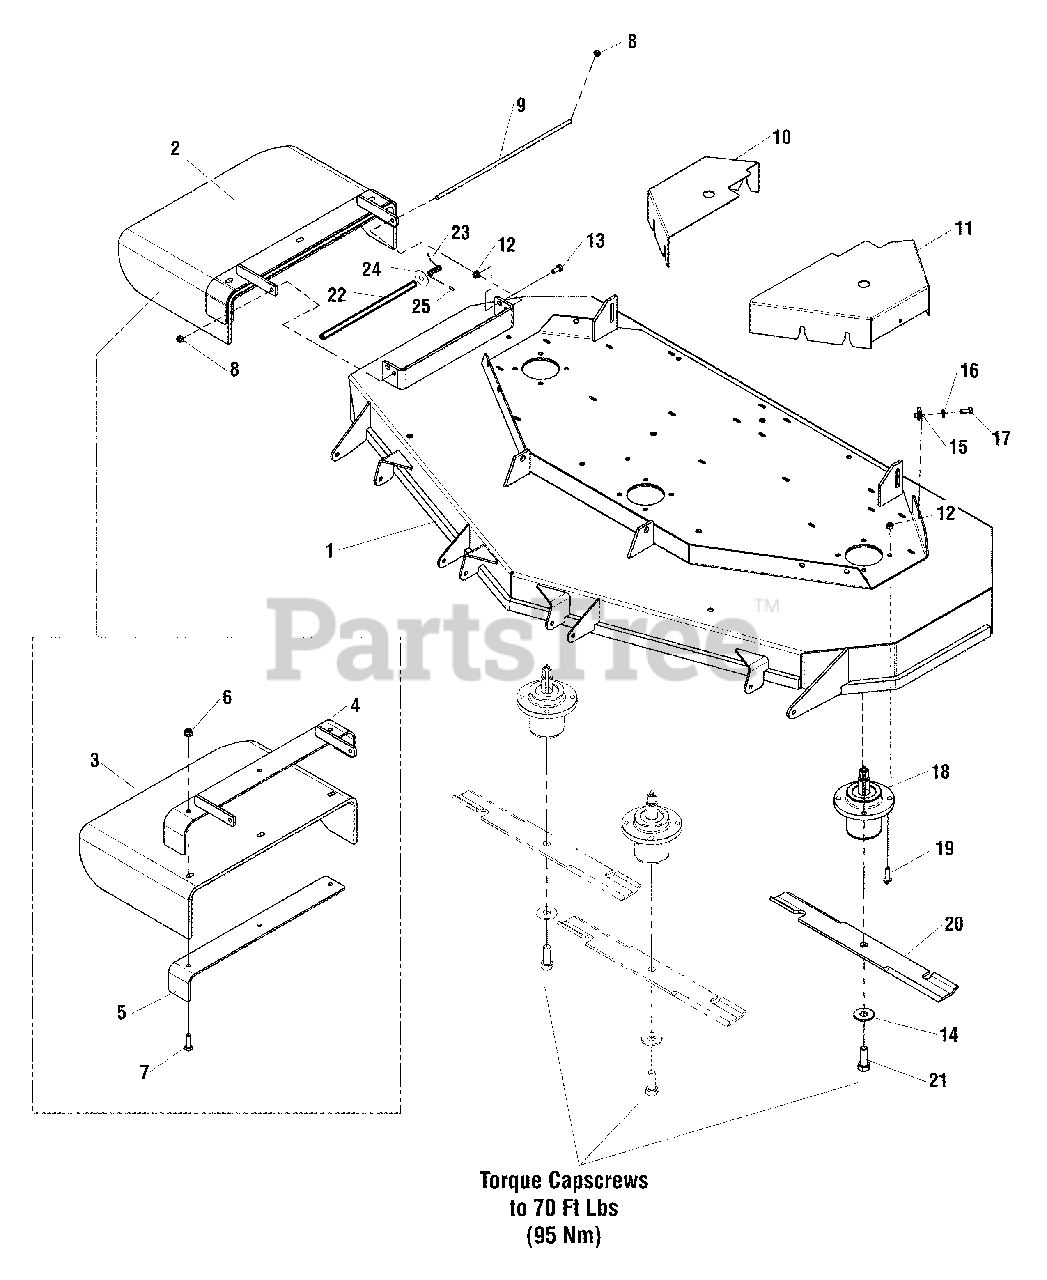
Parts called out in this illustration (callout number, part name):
1	DECK SHELL W/DECALS, 61" - ORANGE
2	ORDER INDIVIDUAL PIECES TO SERVICE DISCHARGE CHUTE COMPONENTS
3	CHUTE, DISCHARGE, RUBBER, 61
4	WELD, FRAME, CHUTE, 61 - ORANGE
5	SUPPORT, DISCHARGE CHUTE - BLK
6	NUT, 3/8-16 HEX NYLOCK FLANGE
7	BOLT, 3/8-16 X 1-1/4" GD5
8	NUT, 5/16-24 HEX NYLON LOCK
9	ROD MOUNT, CHUTE 61"
10	GUARD, 61", RH - ORANGE
11	GUARD, 61" - LH - ORANGE
12	NUT, 5/16-18 HEX NYLOCK FLANGE
13	SCREW-HEX WZ LOCK FLNG 5/16-18X0.750BLK
14	WASHER, 5/8" USS
15	BODY CLIP, 5/16-18 X 1/2" DEEP
16	WASHER, 5/16" SAE
17	BOLT, 5/16-18 X 3/4" GD5
18	ASSM, SPINDLE, LOW PROFILE
19	BOLT, 5/16-18 X 1 1/4" FLANGE
21	BOLT, 5/8-11 X 1-3/4" GD8
22	TORSION SPRING SPACER
23	TORSION SPRING
24	WASHER, 5/16" Fender
